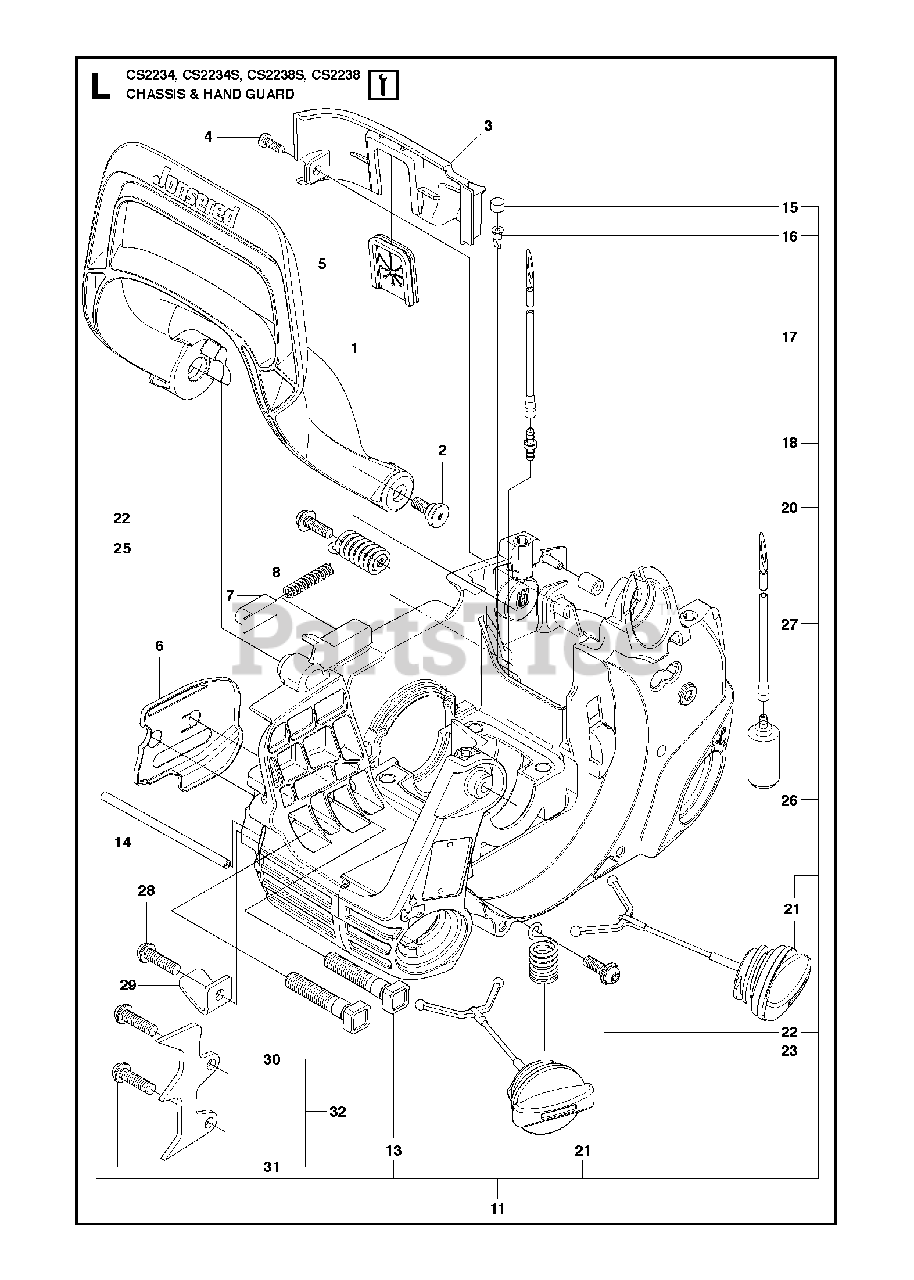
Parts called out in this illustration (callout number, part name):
1	HAND GUARD
2	BOSS SCREW
4	TANK CAP ASSY
6	PLATE BAR
7	CAP, SPRING HANDGUARD
13	BOLT
14	OIL TUBE
15	VENT,FUEL TANK 36/41
16	VALVE-CHECK (DUCKBILL)
17	LINE KIT
18	FUEL LINE FITTING
20	ISOLATOR FILTER HOUSING
21	ASSY CAP FUEL/OIL
22	SCREW,FRONT HBAR 36/41
23	ISOLATOR
25	SPRING
26	FUEL PICK-UP ASSY
27	FUEL LINE
29	CHAIN CATCHER 36/41
30	SPIKE
31	SCREW
32	SPIKE 36/41
